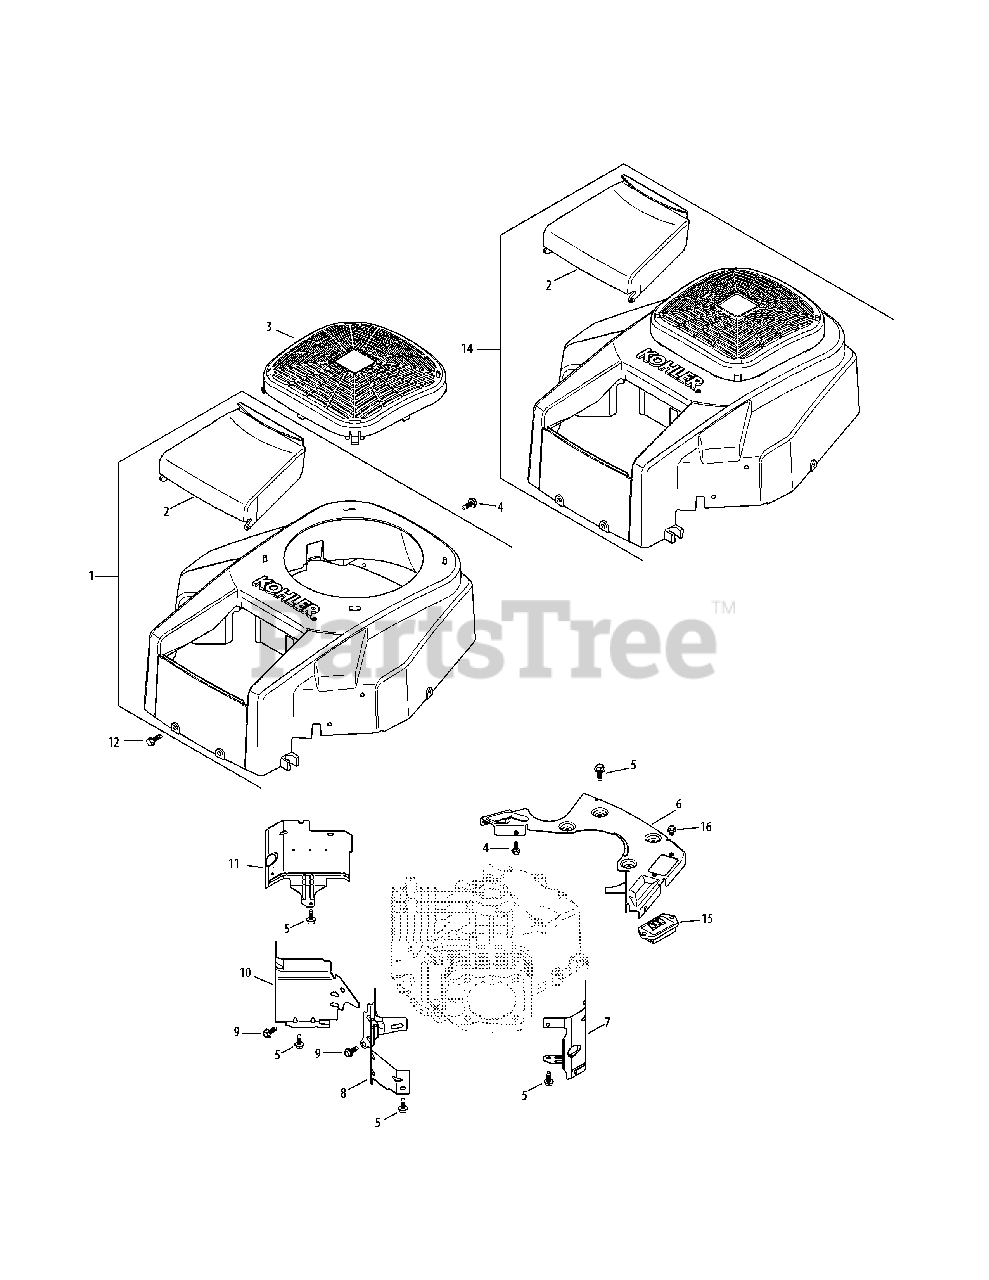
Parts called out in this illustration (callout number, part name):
1	Housing Blower Kit (Inc. 2 & KH-41-037-10-S)
2	Air Cleaner Cover
3	Not used in this application
4	Flg. Thd. Frm. Screw, M5 X 0.8 X 16
5	Flg. Thd. Frm. Screw, M6 X 1.0 X 16
6	Backing Plate Kit
7	Cyl. Barrel Baffle - #2 Side
8	Valley Baffle - #2 Side
9	Flg. Thd. Frm. Screw, M5 X .8 X 10
10	Valley Baffle - #1 Side
11	Cyl. Barrel Baffle - #1 Side
12	Tap Screw, M6 X 1.7 X 18
14	Not used in this application
15	Regulator/Rectifier
16	Flg. Thd. Frm. Screw, M6 X 1.0 X 10
